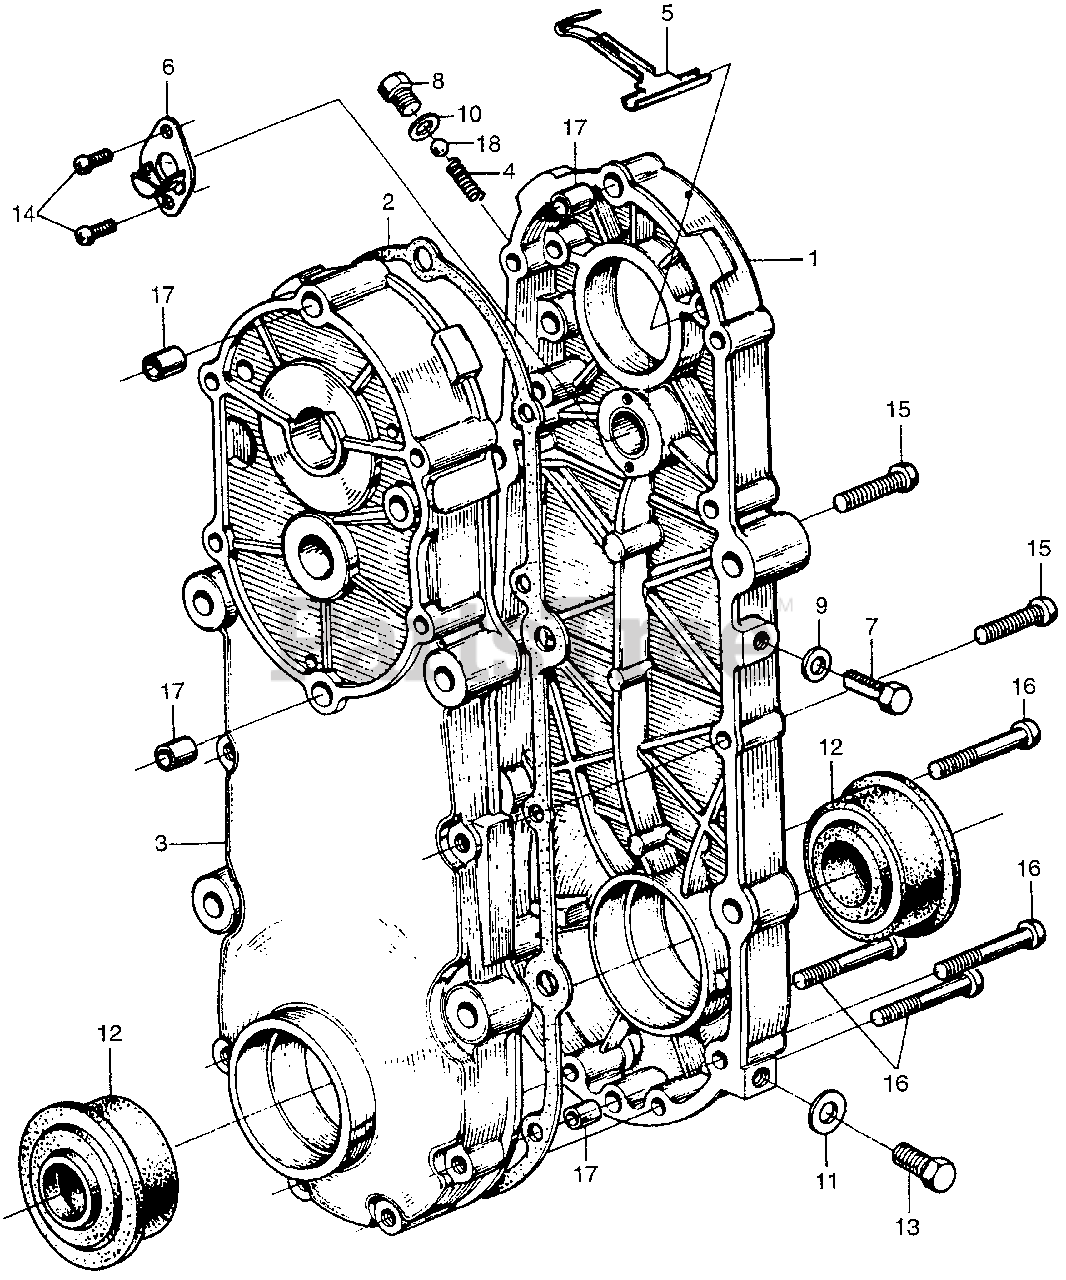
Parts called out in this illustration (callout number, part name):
1	CASE, R. (NOT AVAILABLE)
2	GASKET, CASE (NOT AVAILABLE)
3	CASE, L. (NOT AVAILABLE)
4	SPRING, BALL SETTING
5	GUIDE, OIL (NOT AVAILABLE)
6	RECEIVER, OIL (NOT AVAILABLE)
7	BOLT, OIL CHECK
8	BOLT, HEX. (8X8)
9	WASHER A (6MM)
10	WASHER A (8MM)
11	GASKET, DRAIN PLUG
12	SEAL, WATER (25X46X18)
13	BOLT, DRAIN PLUG (12MM)
14	SCREW, PAN (5X8)
15	SCREW, PAN (6X25)
16	SCREW, PAN (6X32)
17	PIN A, DOWEL (8X10)
18	BALL, STEEL (#8) (1/4)
